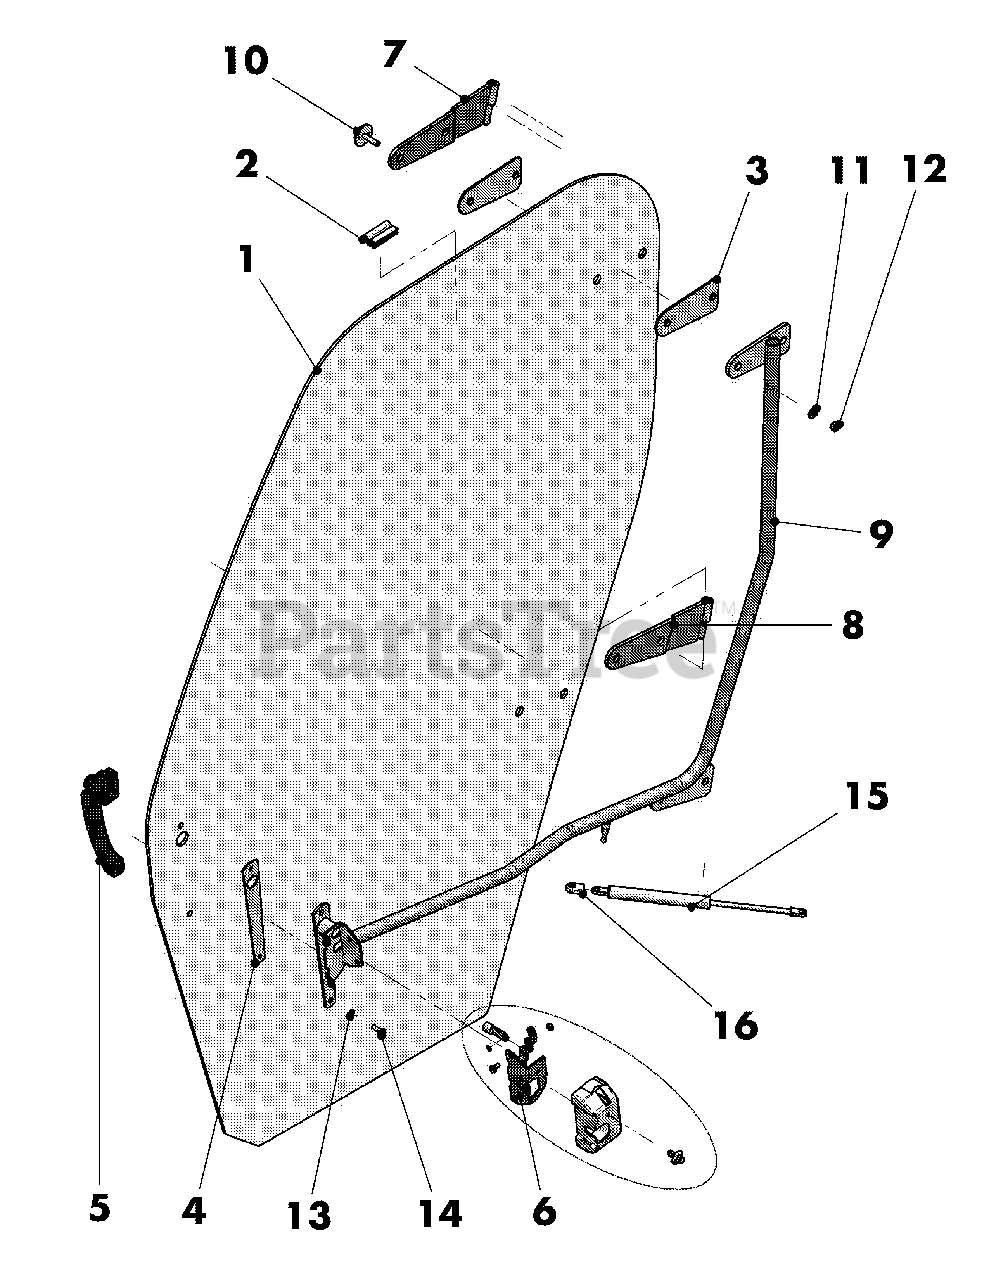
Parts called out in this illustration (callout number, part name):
7	Door Cone - Top RH
7	Door Cone - Top LH
8	Door Cone - Below RH
8	Door Cone - Below LH
9	Door Bail - RH
9	Door Bail - LH
15	Spring - Pneumatic
